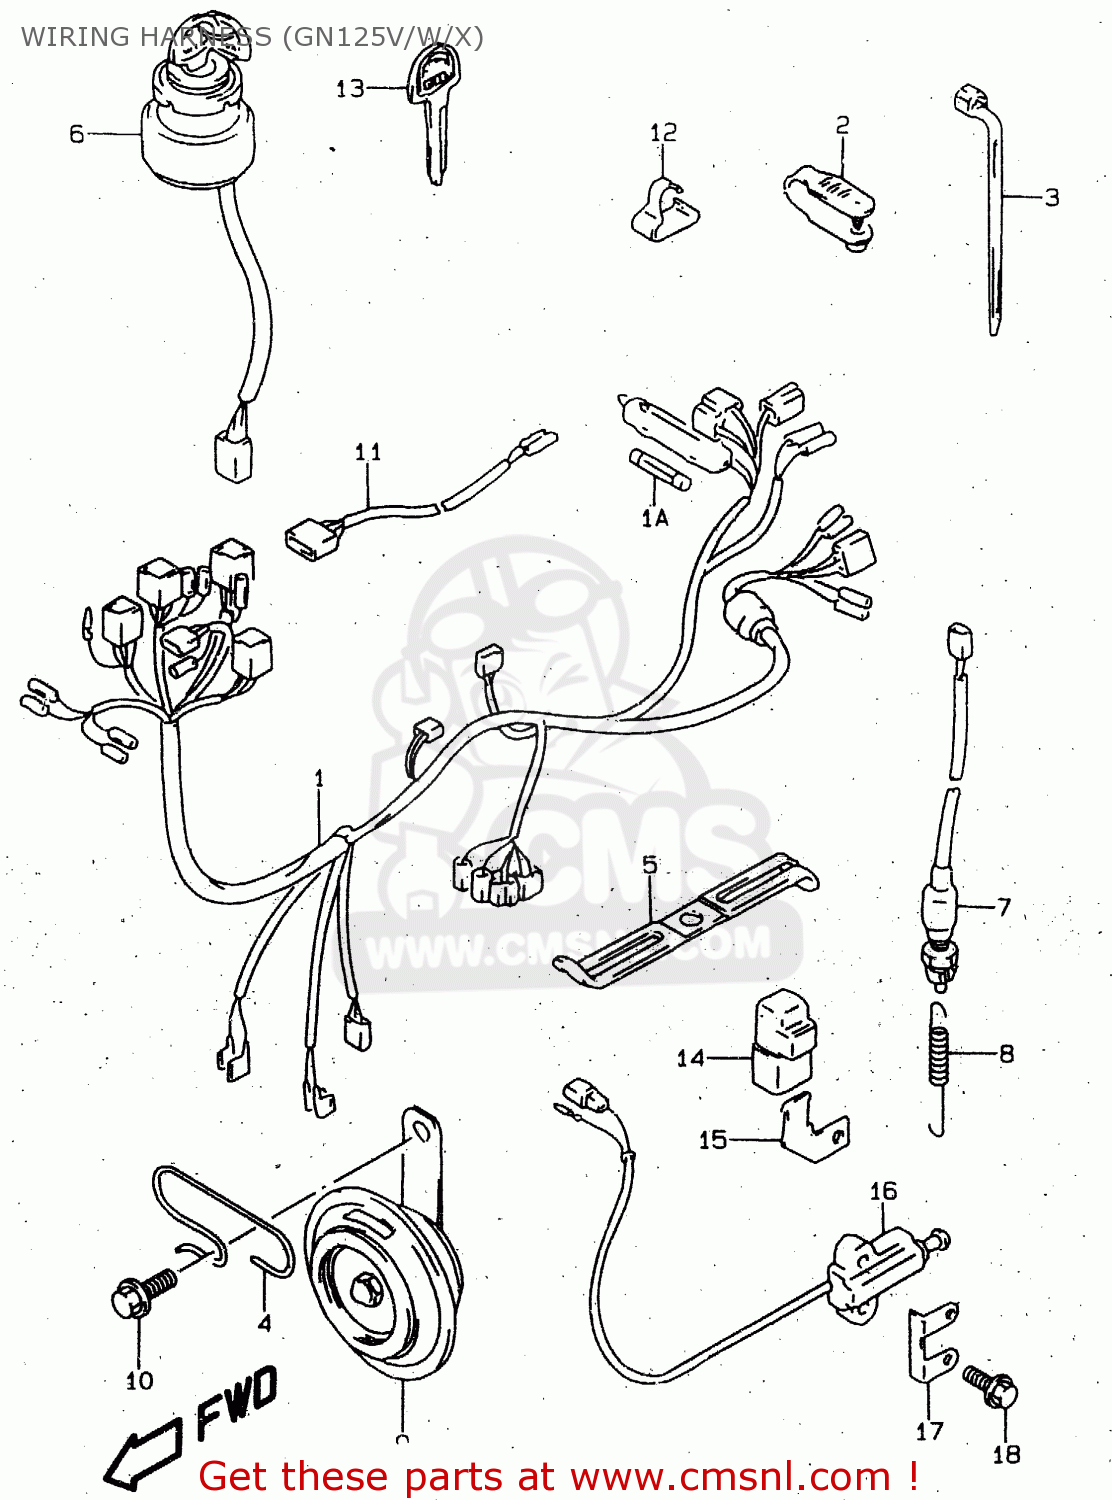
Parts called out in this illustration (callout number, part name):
1	WIRING HARNESS
1A	FUSE(15A)
2	CLAMP,L:88
3	CLAMP L:165
4	CLAMP,WIRING HARNESS
5	CLAMP,STARTER MOTOR LEAD
6	SWITCH ASSY,IGNITION
7	SWITCH ASSY,STOP LAMP
8	SPRING
9	HORN ASSY
10	BOLT
11	WIRE,CLUTCH SWITCH LEAD
12	HOLDER,FUSE CASE
13	KEY,BLANK
14	RELAY ASSY
15	BRACKET,SIDE STAND RELAY
16	SWITCH ASSY,SIDE STAND
17	PROTECTOR,SIDE STAND SWITCH
18	BOLT
